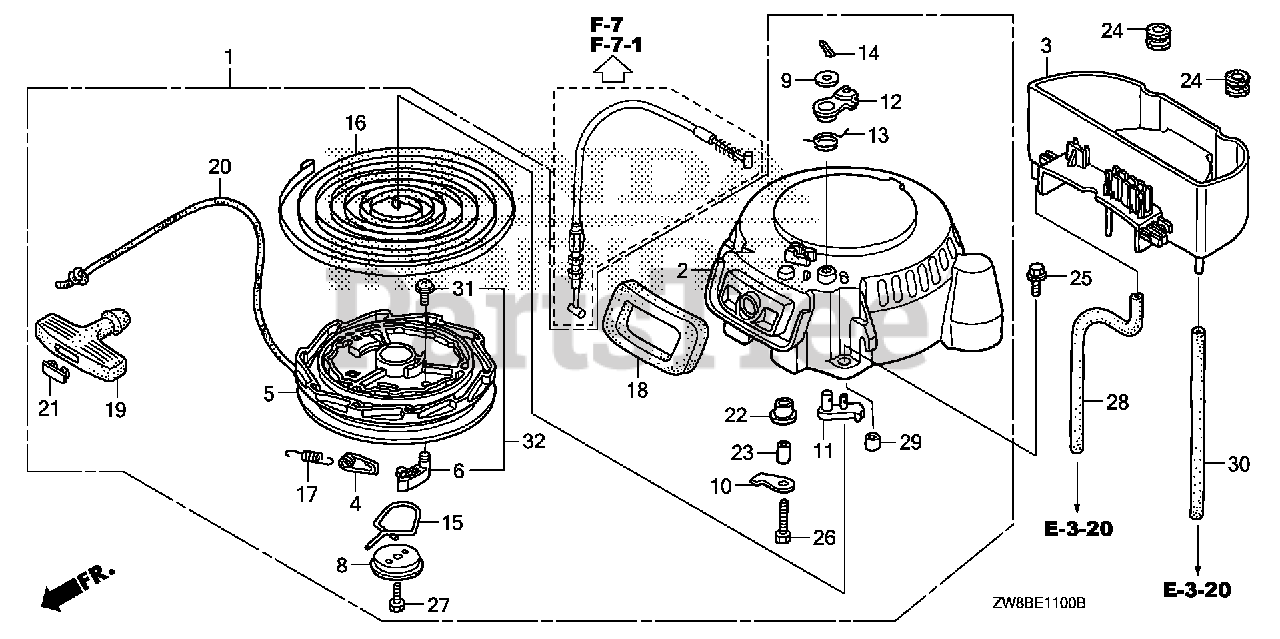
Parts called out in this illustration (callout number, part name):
1	STARTER ASSY., RECOIL
2	CASE, RECOIL STARTER
3	CASE B, STARTER
4	GUIDE, RECOIL STARTER
5	REEL, RECOIL STARTER
6	RATCHET, STARTER
8	PLATE, FRICTION
10	WASHER, THRUST
11	STOPPER, REEL
12	ARM, STOPPER
13	SPRING, STOPPER
14	PIN, SPLIT
15	SPRING, FRICTION
16	SPRING, RECOIL STARTER
17	SPRING, RETURN
18	SEAL, RECOIL
19	GRIP, STARTER
20	ROPE, RECOIL STARTER (#5X73") (N/A: USE P/N 08550-ZG921-11)
21	CAP, STARTER KNOB
22	ROLLER, STARTER
23	GUIDE, ROLLER
24	GROMMET, ENGINE COVER
25	BOLT, FLANGE (6X22)
26	BOLT, HEX. (6X25)
27	BOLT, HEX. (6X14)
28	TUBE, WATER DRAIN
29	COLLAR (6.5X11X10)
30	BULK HOSE, VACUUM (8X1000) (Honda Code 5339163). (8X100)
31	SET SCREW
32	RATCHET SET, STARTER
